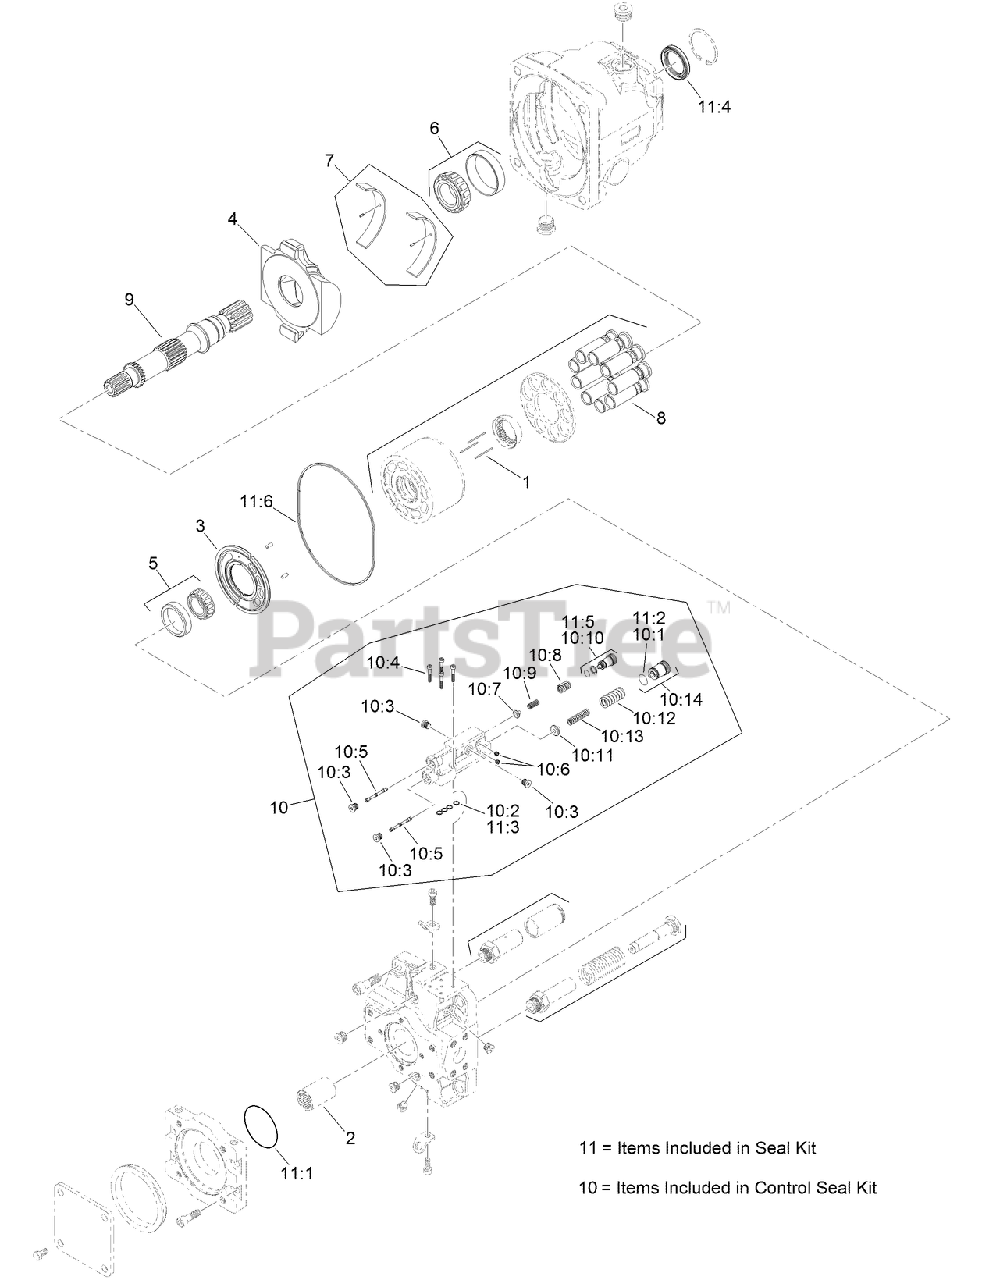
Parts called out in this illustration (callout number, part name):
1	PIN-HOLD DOWN
2	COUPLING
3	PLATE-VALVE, CW
4	SWASHPLATE ASM
5	REAR BEARING KIT
6	FRONT BEARING KIT
7	SWASHPLATE BEARING KIT
8	PISTON ASM
10	CONTROL KIT
10:1	O-RING
10:2	RING-SEAL
10:3	Plug
10:4	Screw
10:5	Spool-Control
10:6	Screw-Set
10:7	GUIDE-SPRING, LS
10:8	SPRING-OUTER, LS
10:9	SPRING-INNER, LS
10:10	PLUG-ADJUSTMENT
10:11	GUIDE-SPRING, PC
10:12	SPRING-OUTER, PC
10:13	SPRING-INNER, PC
10:14	PLUG-ADJUSTING, PC
11	OVERHAUL SEAL KIT
11:1	O-RING
11:2	O-RING
11:3	RING-SEAL
11:4	SEAL-LIP
11:5	PLUG-ADJUSTMENT
11:6	SEAL-CAP, END
